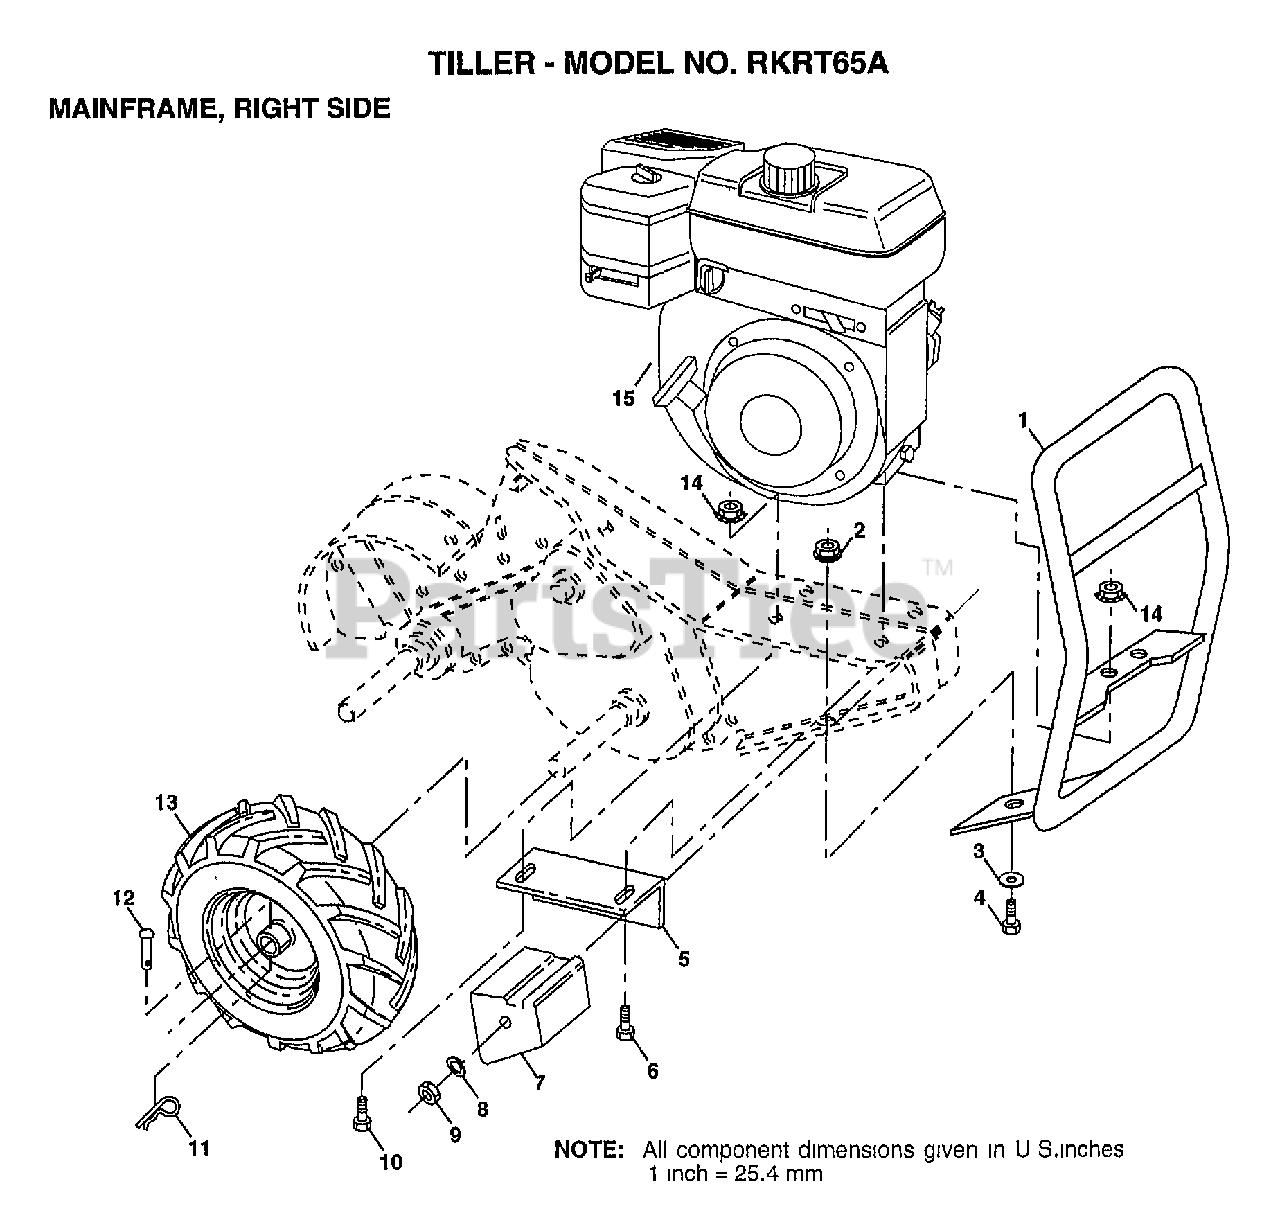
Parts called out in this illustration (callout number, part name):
1	BUMPER ASM.TILLER
2	LOCKNUT TI
3	WASHER
4	BOLT
5	BRACKET RH CRT
6	BOLT
7	COUNTERWEIGHT CRT
8	LOCKWASHER
9	NUT.HEX.3/8-16UNC
10	BOLT.HEX.5/16-1.5
11	RETAINER M
12	RIVET.DRILL.1.75
13	TIRE TI
13	RIM
